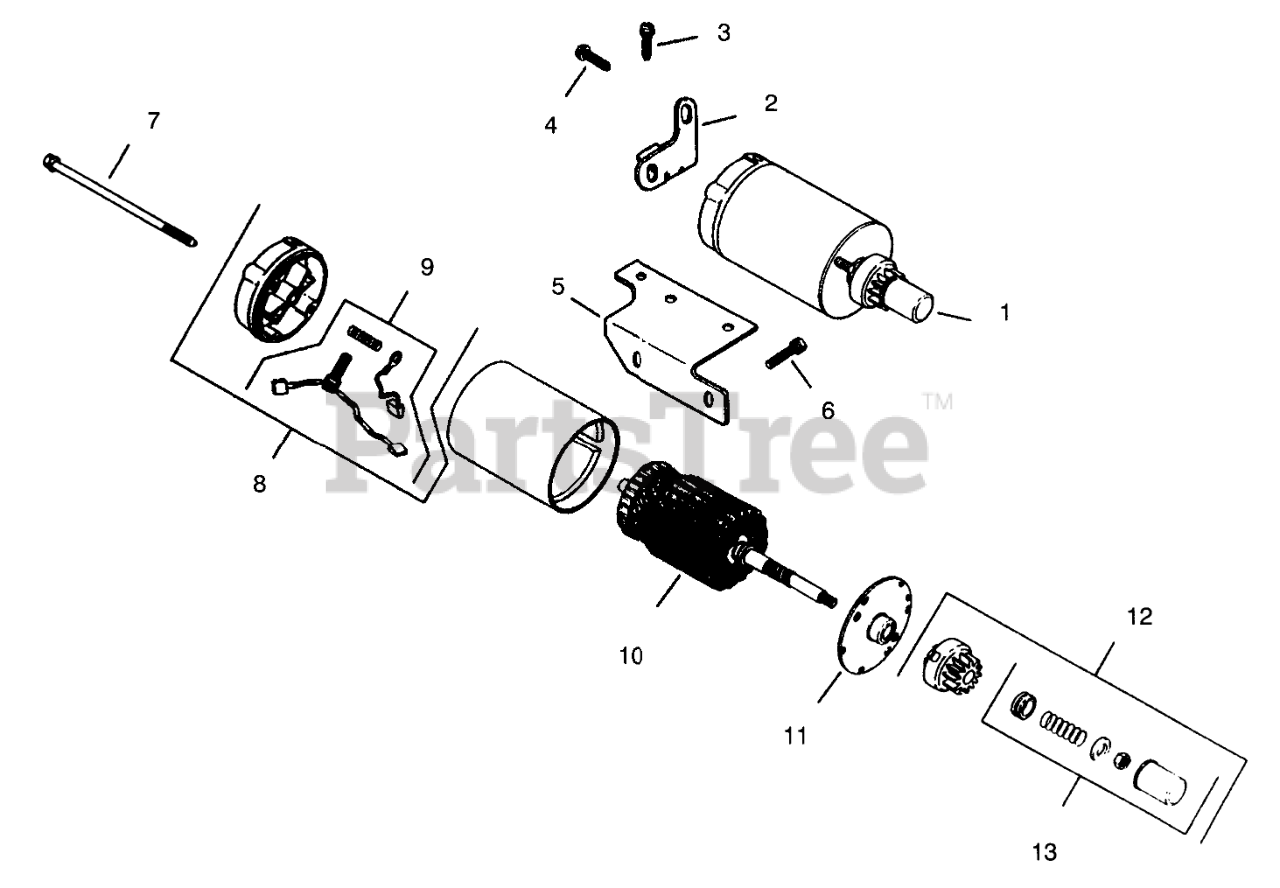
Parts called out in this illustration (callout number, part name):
1	Starter Assembly (Includes Items 9 thru 15)
2	Brace-Starter Tail
3	Screw-Hex. Hd.
4	Screw
5	Bracket-Starter
6	Screw
8	End Cap Ass-Y (Incl. Ref. #9)
9	Brush Kit
10	Armature
11	Cap-Drive End
12	Kit-Drive (Incl. Ref. #15)
13	Drive Parts Kit
